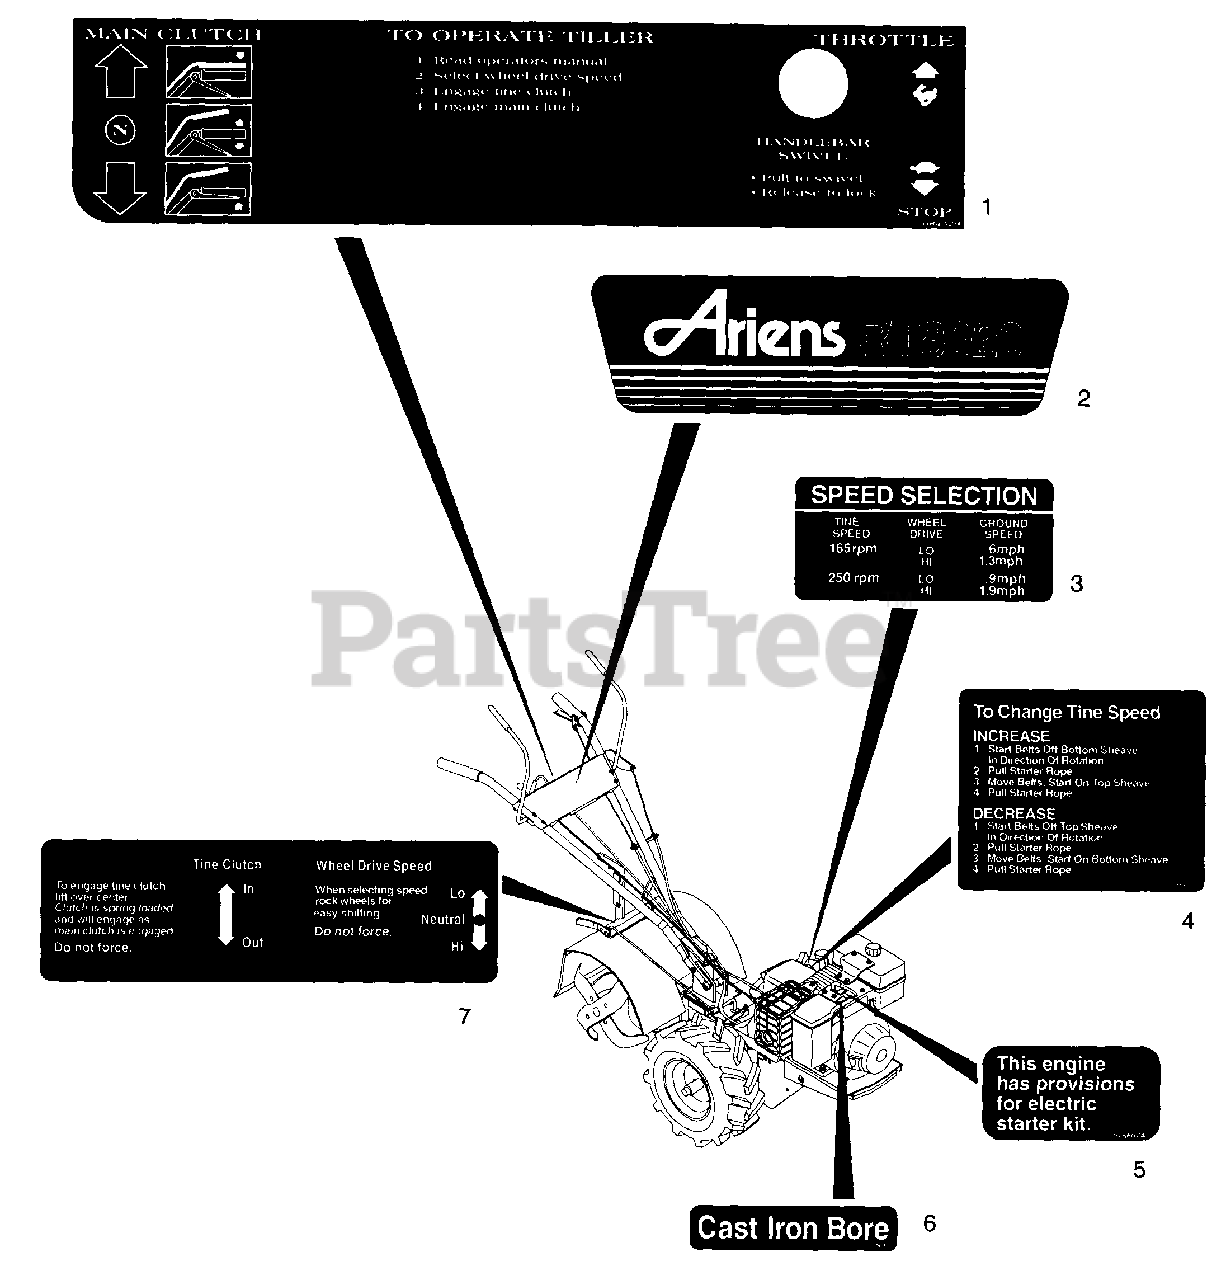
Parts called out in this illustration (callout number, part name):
1	DECAL, DASH CONTROL SER.20"
2	DECAL - RT 8020
3	DECAL - SPEED SELECT 165/250
4	DECAL -TINE SPEED CHANGE
5	DECAL, ELECTRIC START
6	DECAL - CAST IRON BORE
7	DECAL - TINE CLUTCH-DR SPEED
